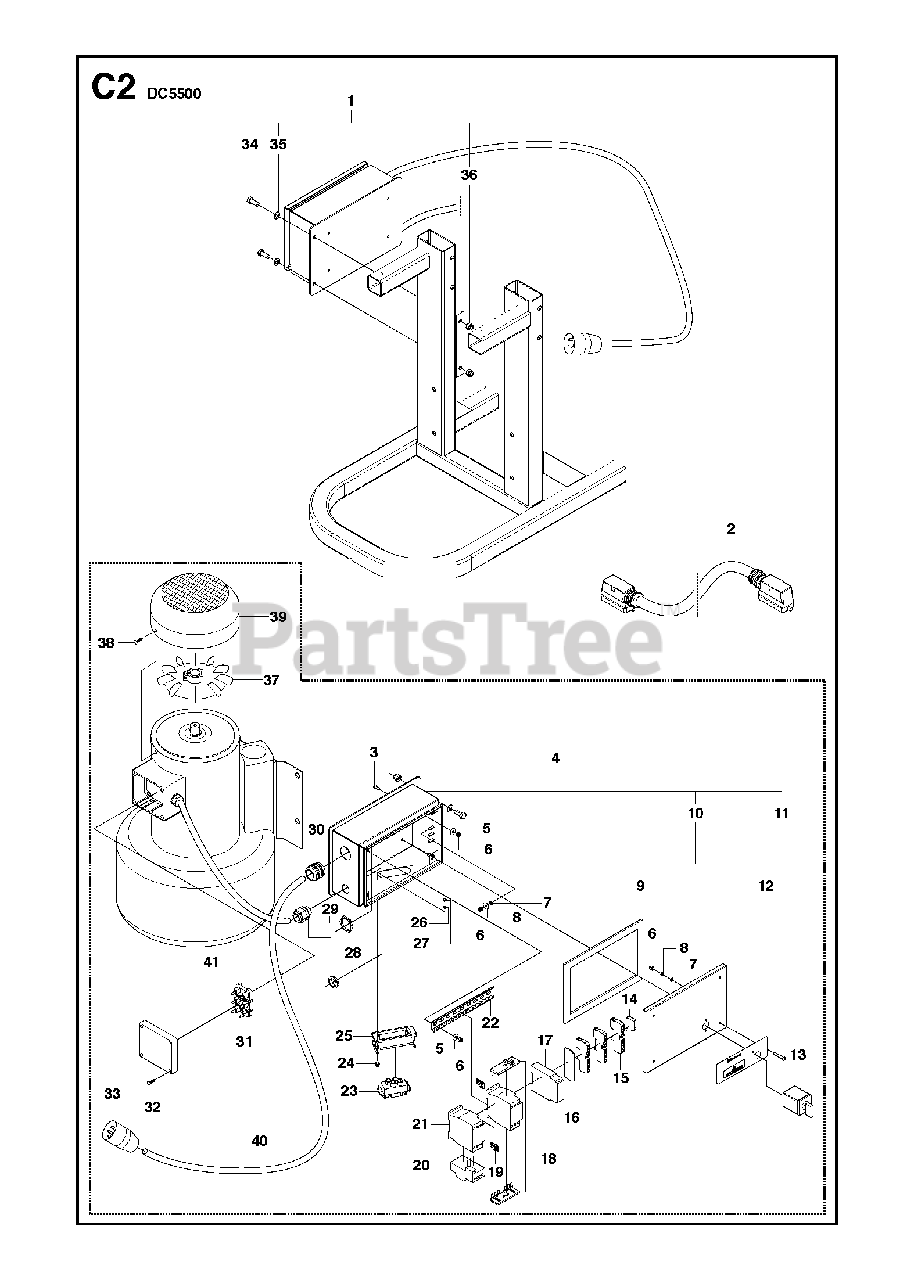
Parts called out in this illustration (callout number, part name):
6	HEXAGON LOCKING NUT
24	SCREW CRPANM
27	HEXAGON LOCKING NUT
32	SCREW CRPANM
35	WASHER
36	HEXAGON LOCKING NUT
